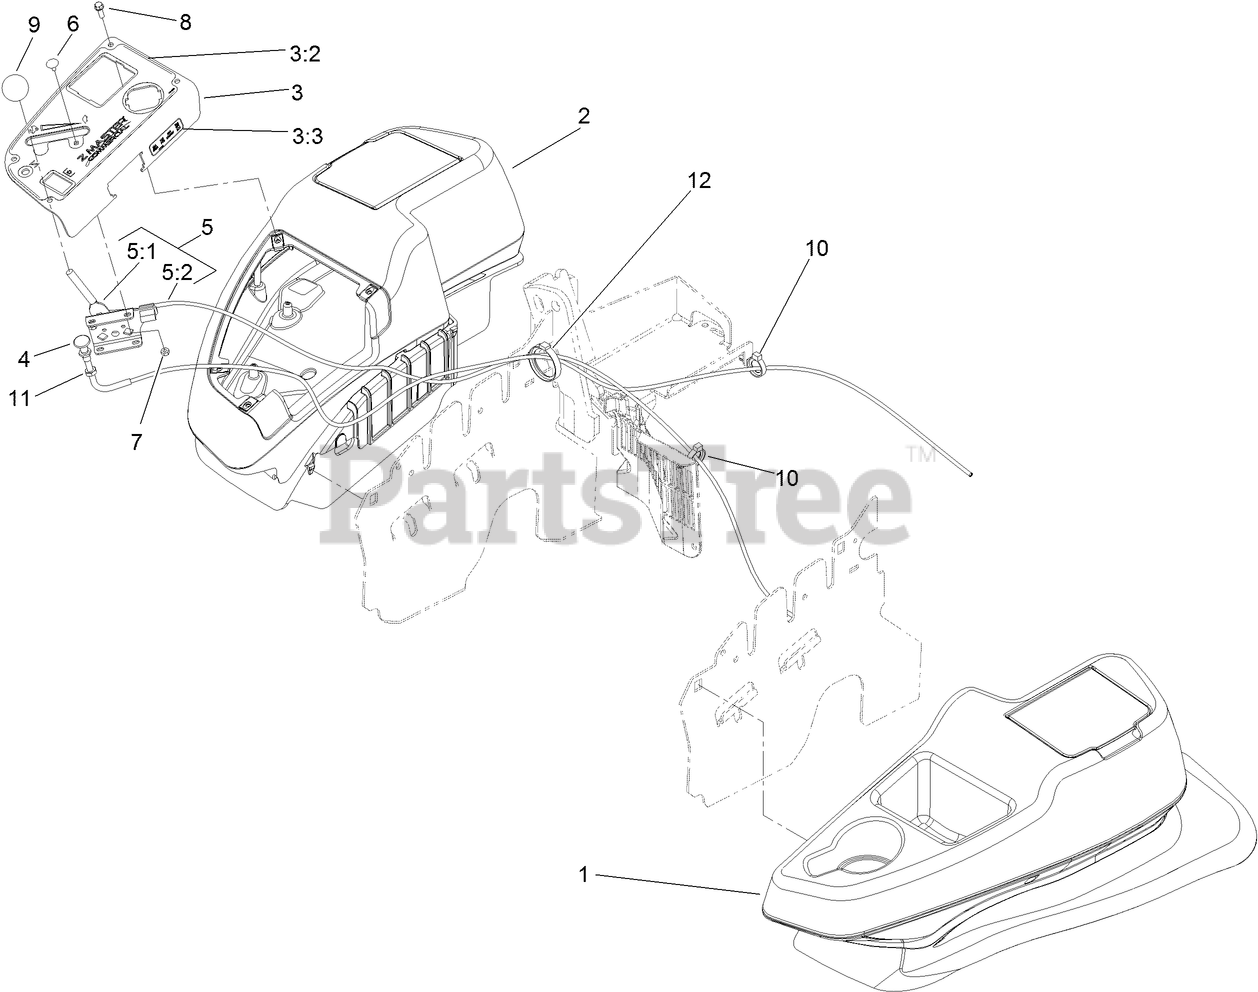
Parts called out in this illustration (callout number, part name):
1	LH CONSOLE ASM
2	RH CONSOLE ASM
3	CONTROL PANEL ASM
3:2	DECAL-PANEL, CONTROL
3:3	DECAL-FUSES
4	CHOKE CONTROL ASM
5	THROTTLE CONTROL ASM
5:1	LEVER-THROTTLE
5:2	CABLE-THROTTLE
6	BOLT-CARR
7	NUT-LOCK, NI
8	SCREW-HWH
9	KNOB-BALL
10	CLAMP-HOSE
11	NUT-HJ
12	CLAMP-HARNESS
